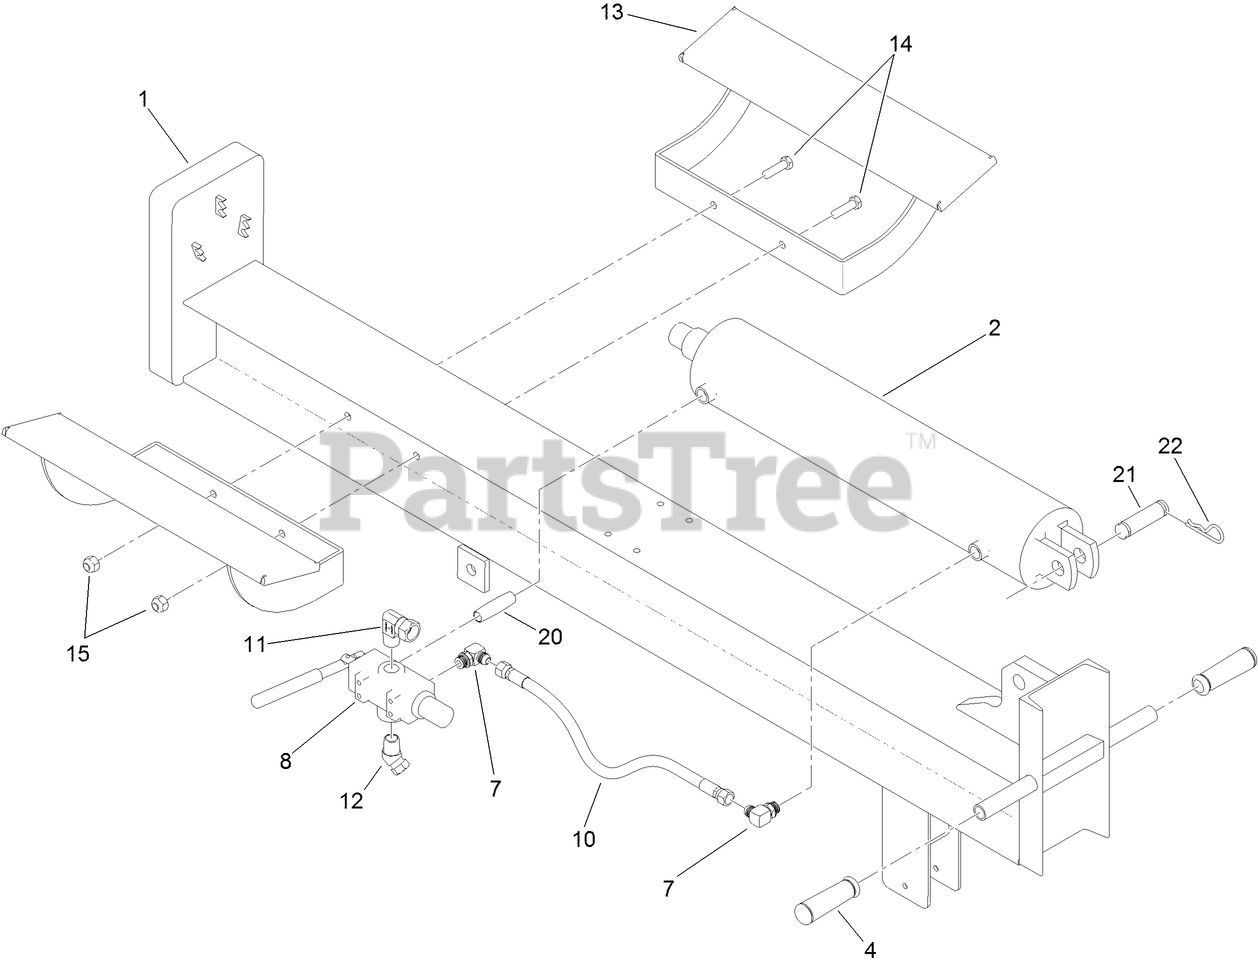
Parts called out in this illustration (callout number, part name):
1	SPLITTER BEAM ASM
2	HYD CYLINDER ASM
4	GRIP-HANDLE
7	FITTING-HYD
8	HYD VALVE ASM
10	HYD TUBE ASM
11	FITTING-HYD, 90DEG
12	FITTING-HYD, 45DEG
13	PLATE-CATCH
14	SCREW-HH
15	NUT-LOCK
20	FITTING-HYD
21	PIN-PIVOT
22	PIN-HAIR
